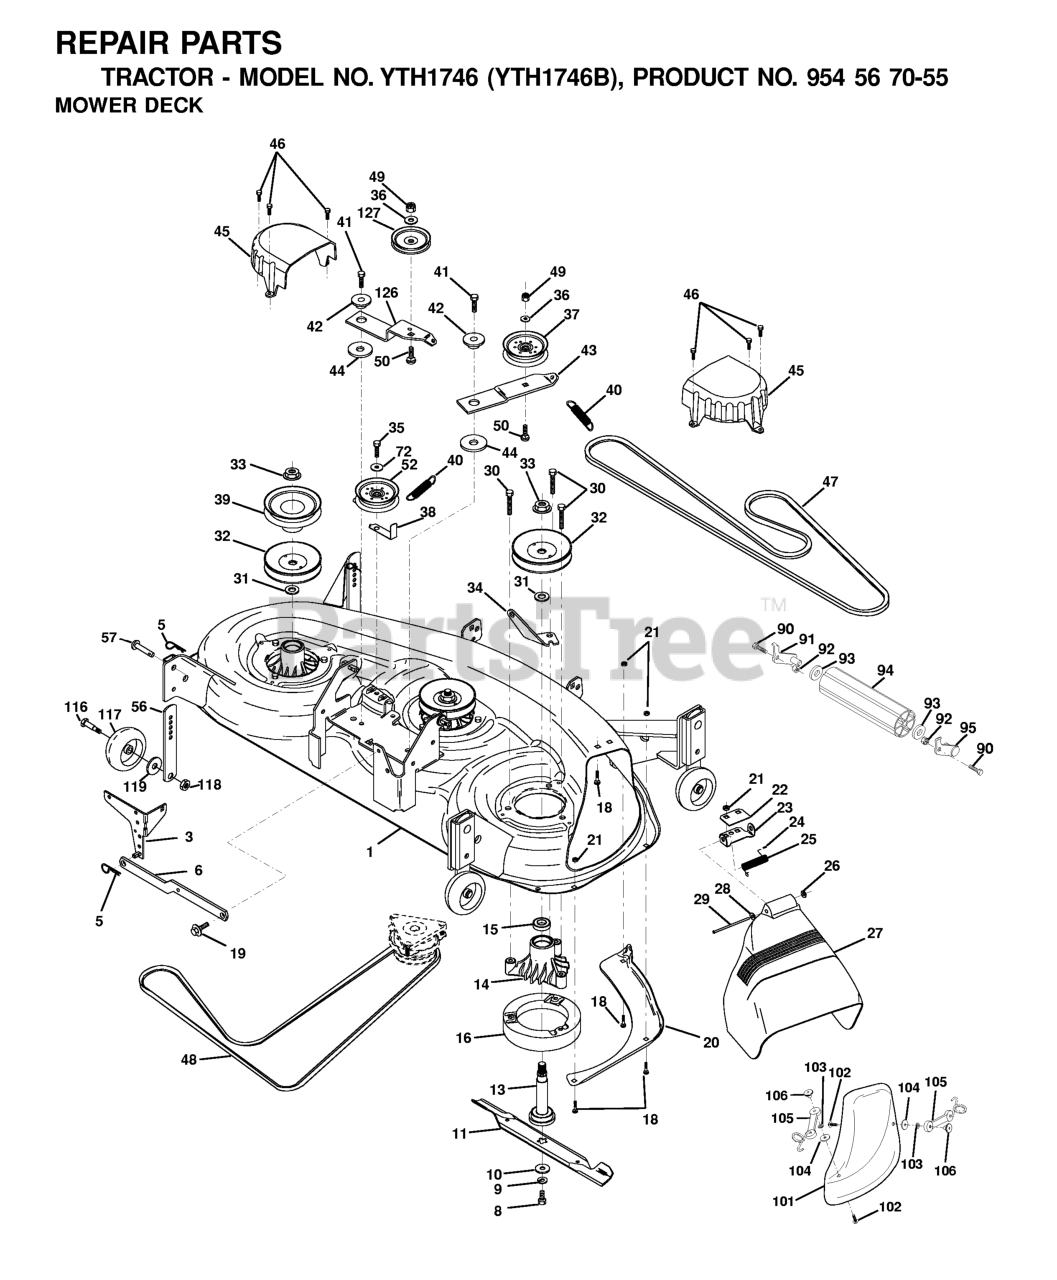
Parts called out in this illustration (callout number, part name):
3	BRACKET SWAY BAR
5	RETAINER-SPRNG RB
6	REAR SUSP ARM
8	BLADE BOLT
9	LOCKWASHER
10	WASHER.BLADE
11	BLADE.46".HI-LIFT.PREMIUM
13	SHAFT.ASM.W/BEARING
14	HOUSING.MANDREL.44/46" VENT
16	STRIPPER.MANDREL.ROUND.BLACK
18	BOLT
19	BOLT SHD 5/16-18
20	BAFFLE, VORTEX MOWER 46"
21	LOCKNUT
24	CAP-SLEEVE LT
25	TORSION SPRING
26	NUT PUSH M
28	Washer 11/32 x 5/8 x 16 Ga SD
29	ROD.HINGE
30	SCREW THDROL ROLLING WASHER HD
31	WASHER
32	MANDREL PULLEY
33	NUT
35	SCREW LT
36	WASHER
37	PULLEY.IDLER.FLAT
40	SPRING.SEC.44"VEN
41	SCREW.3/8-16
42	SPACER RETAINER
44	HARDENED WASHER
45	COVER MANDREL 46
46	SCREW.1/4-20X5/8
47	BELT V SECONDARY
48	V-BELT PRIMARY 50"
50	BOLT.3/8-16X1.50
52	PULLEY.IDLER.FLAT.46".PRIMARY
56	BAR.ADJUST.WHEEL.ANTI.SCALP.BL
57	RIVET.PIN.HEAD.YELLOW.
72	WASHER
90	BOLT
91	BRACKET LH (A)
92	NUT
93	Washer 1 17/32 X 7/8 X 16 Ga
94	NOSE ROLLER
95	BRACKET RH (B)
101	COVER.MULCH.46"3-BLADE.(2 2)
102	SCREW
103	LOCKWASHER #10
105	LATCH ASSY
106	WELDNUT
116	BOLT, SHOULDER
117	WHEEL GAGE DONUT
118	LOCKNUT
119	WASHER.5/16.FLAT.STE.STD.
532152443	MULCH BLADE 46"
